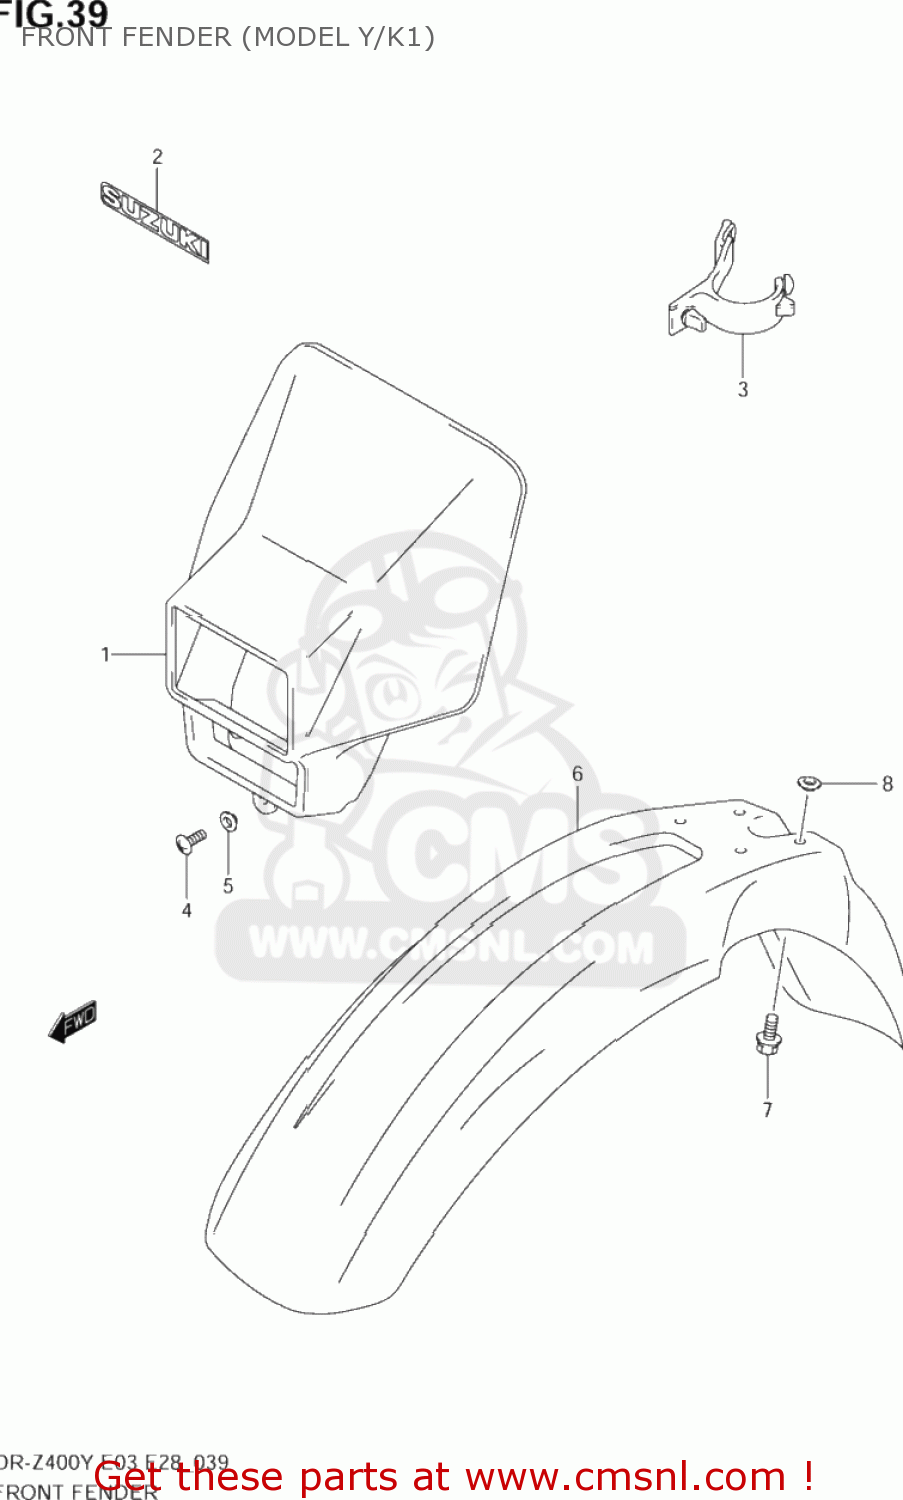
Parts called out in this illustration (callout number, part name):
1	COVER,HEADLAMP
2	EMBLEM,SUZUKI
3	BAND,HEADLAMP COVER
4	SCREW(5X12)
5	WASHER
6	FENDER,FRONT
7	BOLT(6X16)
8	WASHER
